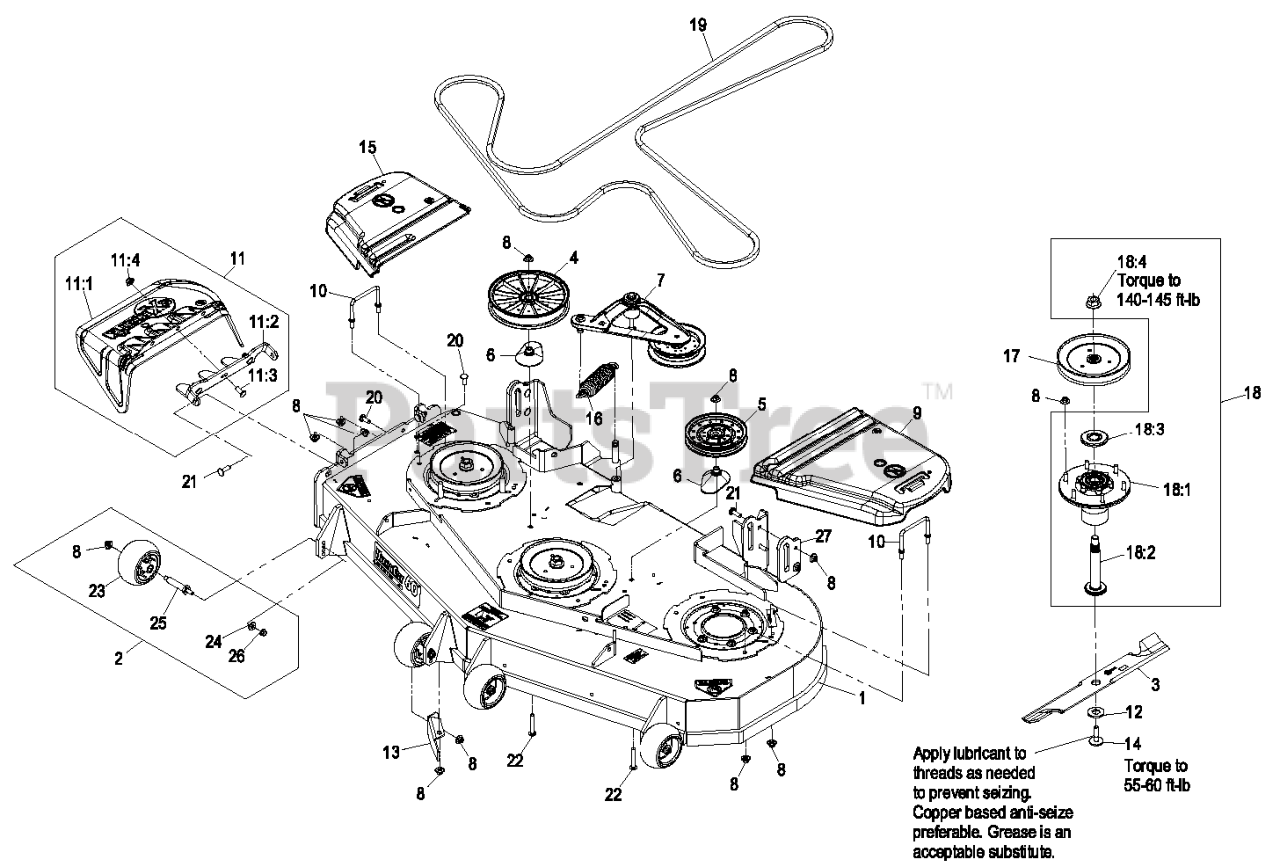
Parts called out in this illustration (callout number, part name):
4	PULLEY,IDLER 8"FLAT
6	SPACER-PULLEY
8	Nut-Nyloc 3/8-16 Flg
9	COVER-BELT, LH
10	WIREFORM-COVER
11	ASM,DISCHARGE CHUTE
11:1	CHUTE,DISCHARGE
11:2	BRACKET,DISCHARGE CHUTE
11:3	SCREW-CARR
11:4	Nut-Nyloc 3/8-16 Flg
12	WASHER-BLADE DRIVE
13	BAFFLE,DISCHARGE 52/60
14	BOLT-BLADE, SEM
15	COVER-BELT, RH
17	SHEAVE,BLADE DRIVE 7.25
18:1	ASM,CUTTER HSG WITH BEARI
18:2	SPINDLE,HEX PILOT 5.5" DE
18:3	GUARD,BEARING TOP .989
18:4	NUT-FLANGE
19	BELT,V-5V-198.75
20	SCREW-CARR
21	Bolt-Carriage 3/8-16 X 1 1/4
22	SCREW-CARR
23	ROLLER-SCALP, ANTI
24	WASHER-BELLEVILLE
26	NUT-HHF, WHIZ
28	Asm, Complete Deck
